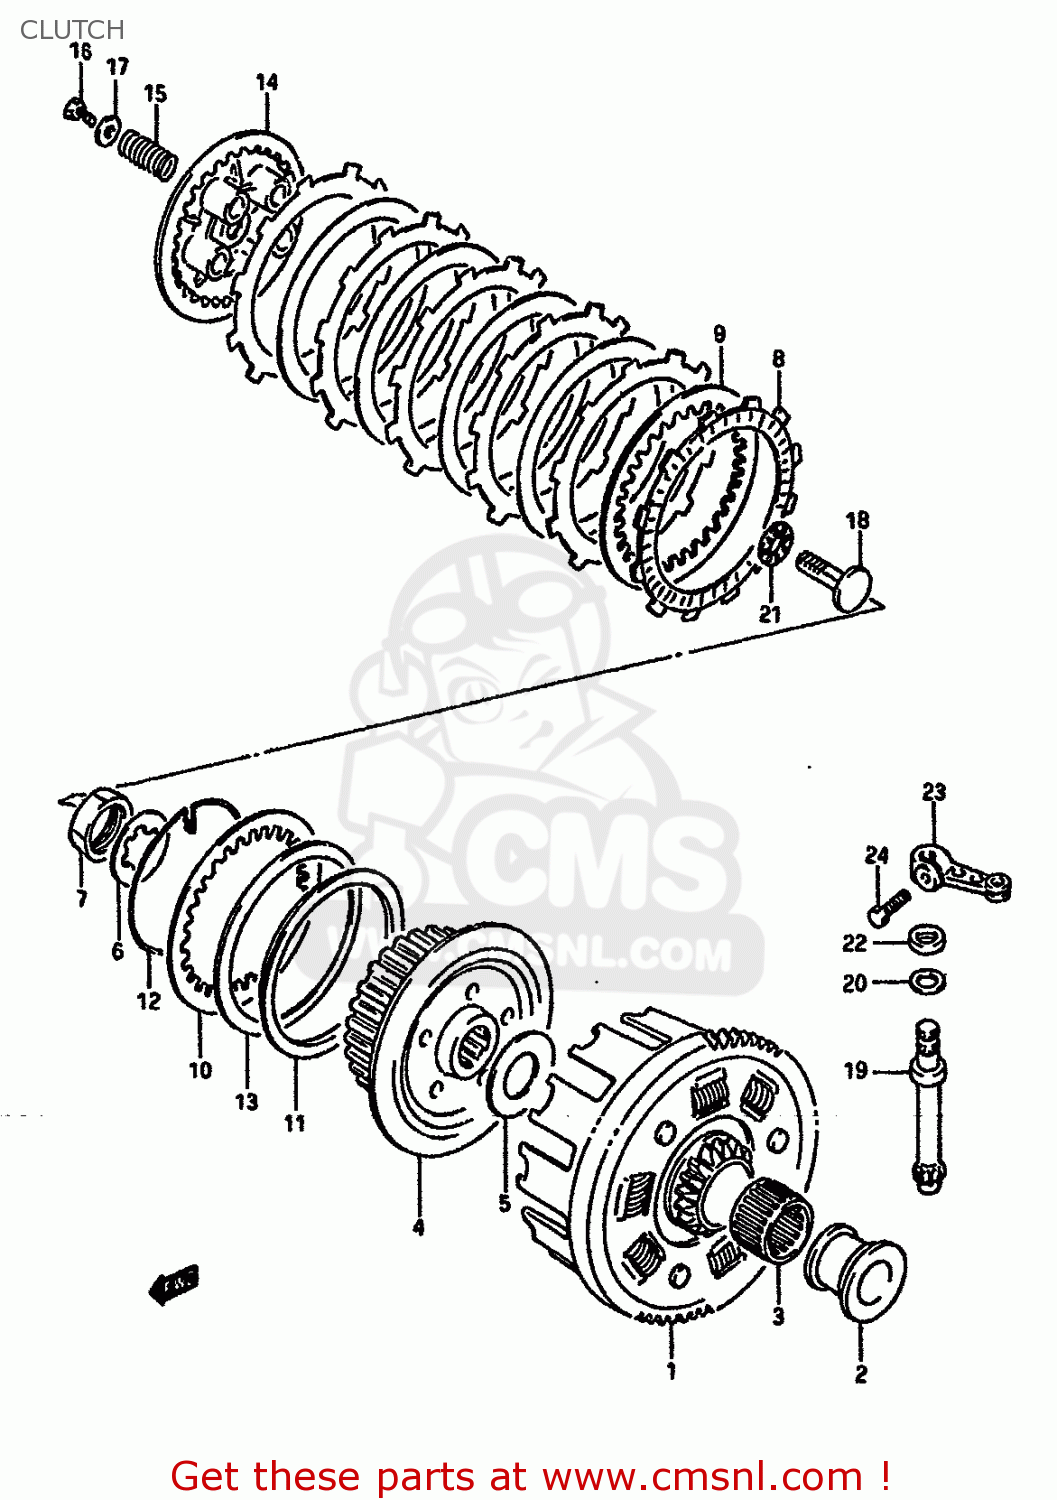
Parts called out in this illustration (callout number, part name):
1	GEAR,PRIMARY DRIVEN
2	SPACER
3	BEARING(25X30X21.8)
4	HUB,CLUTCH SLEEVE
5	WASHER(20X35X2)
6	WASHER,LOCK
7	NUT (20MM)
8	PLATE,CLUTCH DRIVE (NAS)
9	PLATE,CLUTCH DRIVEN (NAS)
10	PLATE,CLUTCH DRIVEN(T:2.0) (NAS)
11	SEAT,WAVE WASHER
12	RING,STOPPER
13	WASHER
14	DISC,CLUTCH PRESSURE
15	SPRING
16	BOLT(5X16)
17	WASHER (5.5X16X1.2)
18	RACK,CLUTCH RELEASE
19	PINION,CLUTCH RELEASE
20	WASHER (12X17X1)
21	BEARING(10X22X2.8)
22	SEAL,OIL(10X17X5)
23	ARM,CLUTCH RELEASE
24	BOLT
